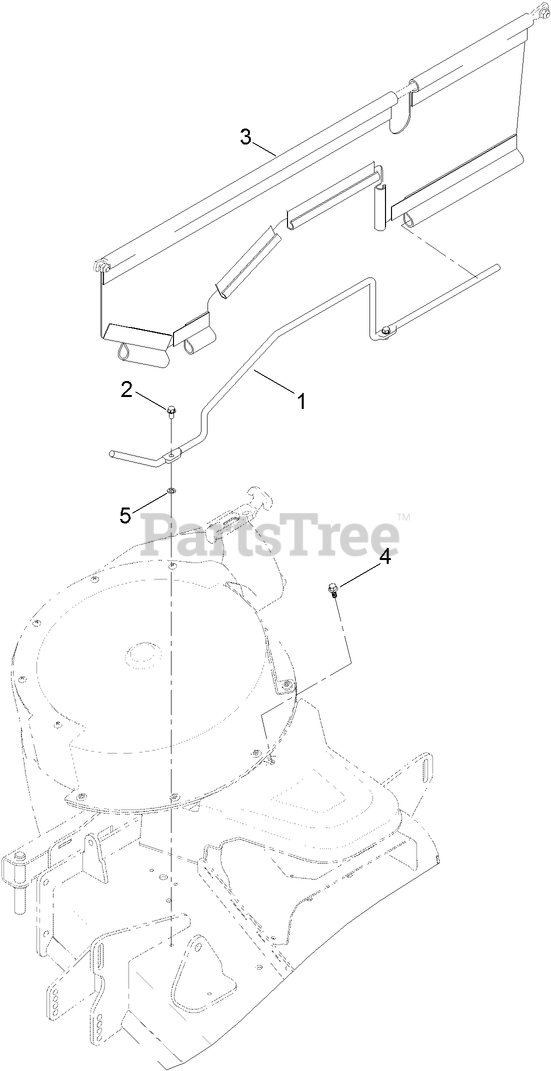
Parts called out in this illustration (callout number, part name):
1	ROD SUPPORT, LOWER
2	SCREW-HWH
3	GUARD-SIDE, POLY KNIT
4	SCREW-HHF
5	NUT-RETAINING
